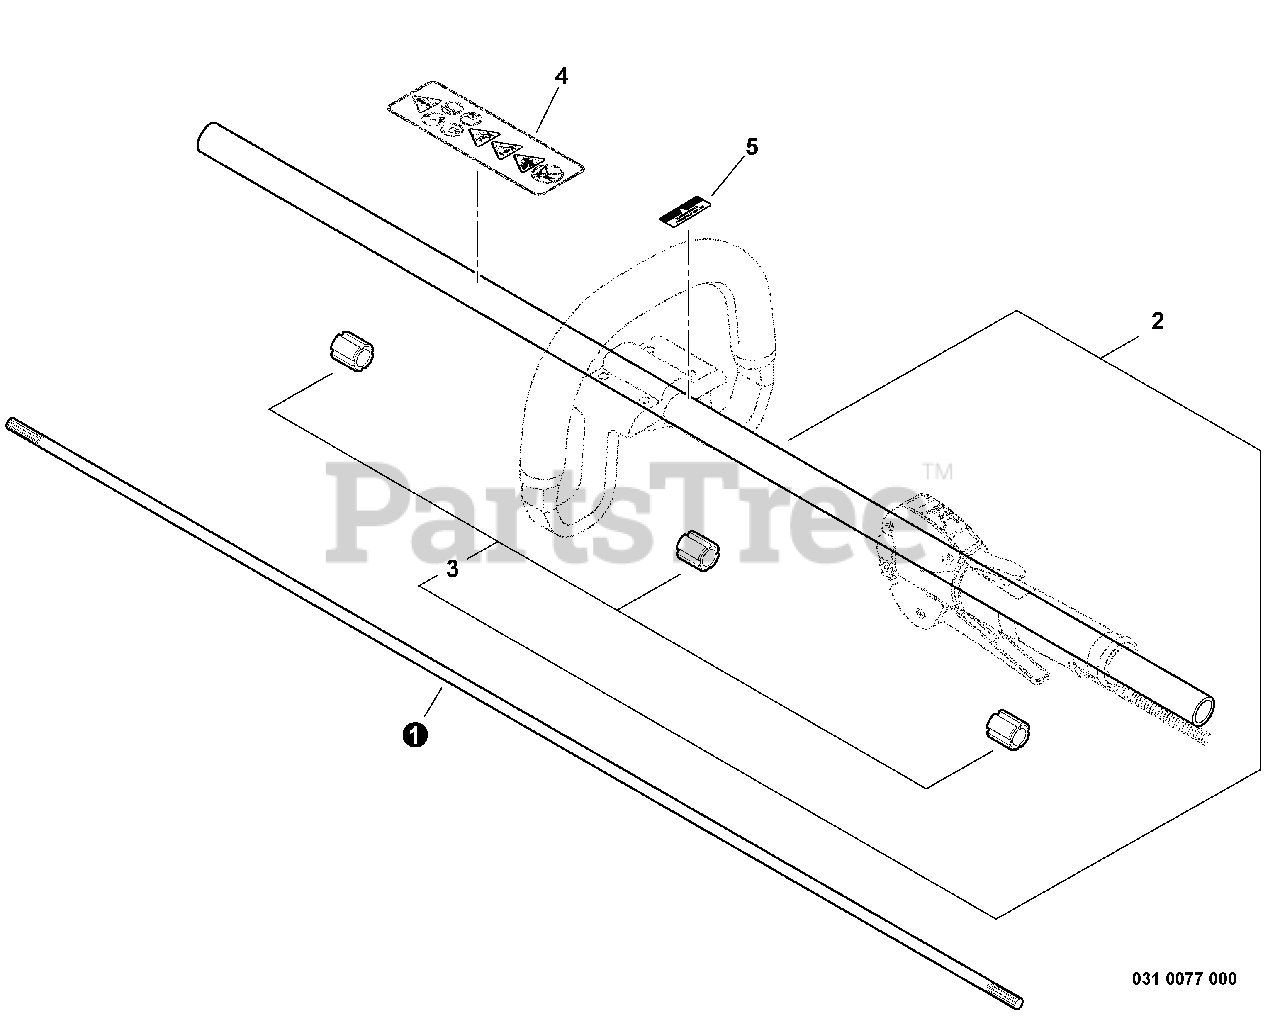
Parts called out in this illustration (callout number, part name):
1	DRIVESHAFT - SOLID
2	MAIN PIPE ASSY
3	BUSHING
4	LABEL - CAUTION
5	LABEL - HANDLE LOCATION
